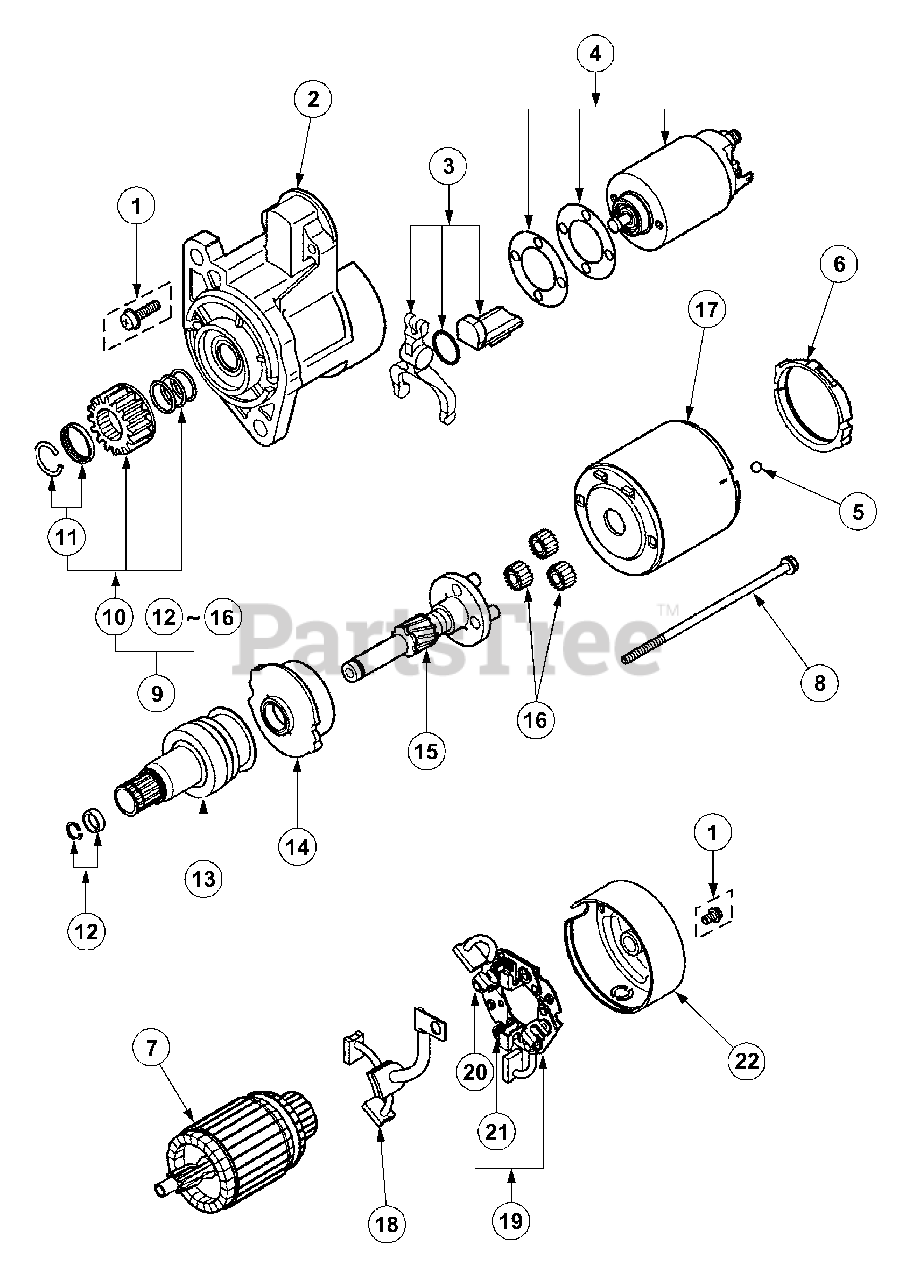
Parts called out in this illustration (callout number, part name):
2	Bracket Ass'y
3	Lever Set
4	Switch Ass'y
7	Armature Set
8	Bolt
9	Shaft Ass'y,Clutch
13	Clutch,Over Run
14	Gear Ass'y,Internal
15	Shaft Ass'y,Gear
17	Yoke Ass'y
18	Brush Ass'y
19	Holder Ass'y,Brush
22	Bracket Ass'y
